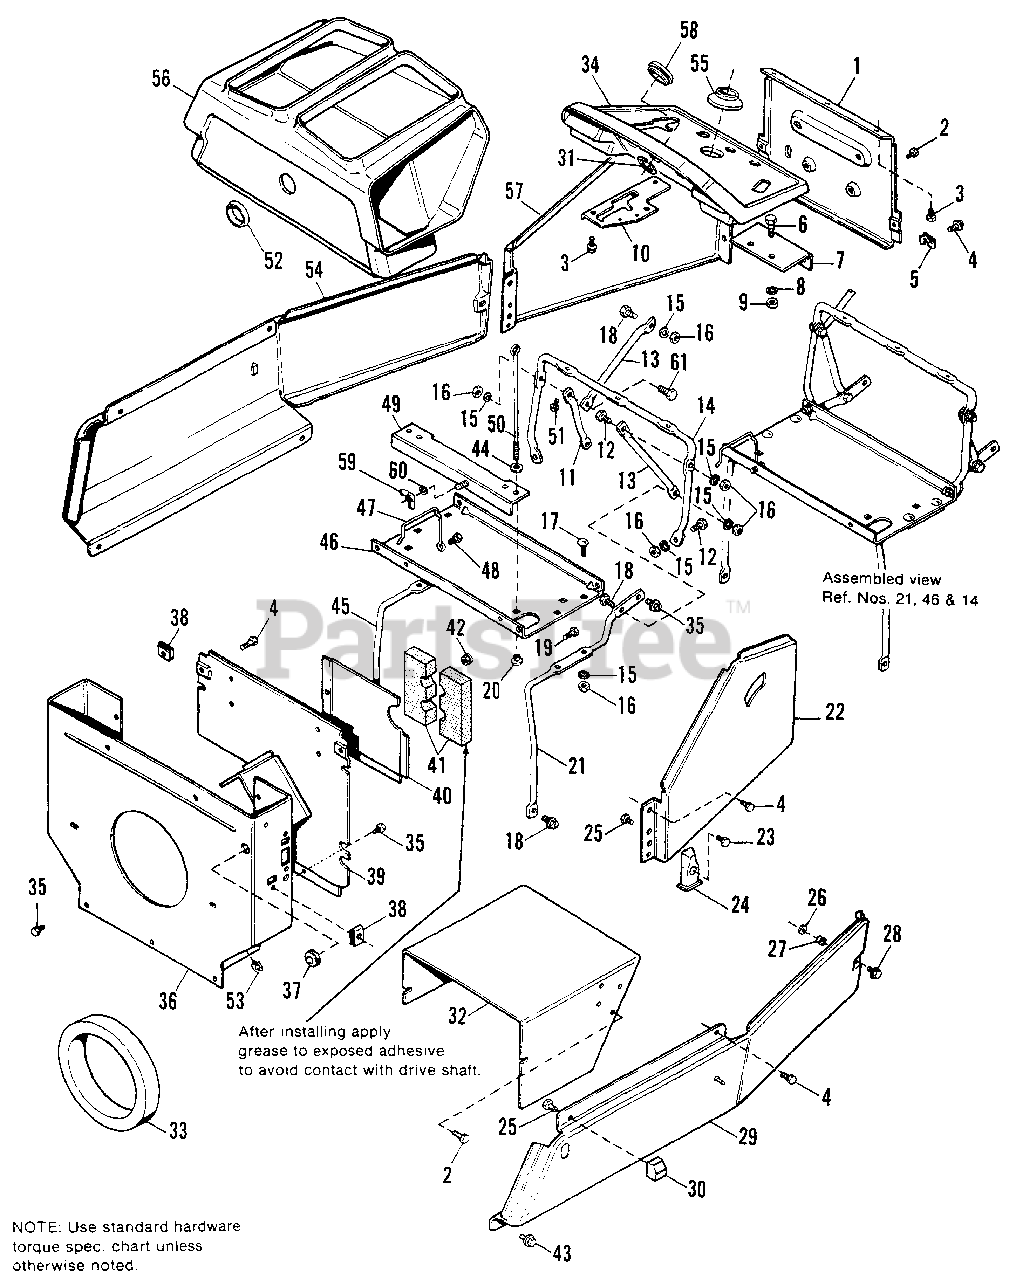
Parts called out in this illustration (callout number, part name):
1	PANEL, Rear Dash
2	SCREW, Hex, Taptite, 1/4-20 x 5/8 (Qty. 7 on 1691381 & 1691710 only)
3	SCREW, Hex, Plastite, 1/4-10 x 5/8
4	SCREW, Hex, Type "AB" 1/4-14 x 5/8
5	SPEED NUT, "J" Type, 14A
6	CAPSCREW, Hex Hd., 3/8-16 x 1
7	BRACKET, Mounting, Dash Panel, Rear
8	LOCKWASHER, 3/8
9	NUT, Hex, 3/8-16
10	PLATE, Speed Control Lever
11	BRACE, Dash Cap Support, R.H.
12	CAPSCREW, Hex Hd., 5/16-18 x 1
13	BRACE, Dash Cap Support, L.H.
14	SUPPORT, Dash Cap
15	LOCKWASHER, 5/16
16	NUT, Hex, 5/16-18
17	BOLT, Carriage, 5/16-18 x 7/8
18	CAPSCREW, Hex, Taptite, 5/16-18 x 3/4
19	CAPSCREW, Hex Hd., 1/4-20 x 3/4
20	NUT, Plastic, 1/4-20
21	SUPPORT, Battery Tray, L.H.
22	DASH PANEL, Upper, L.H.
23	SCREW, Hex, 1/4 x 1
24	GUIDE, Spacer, Hood
25	SCREW, Hex, Plastite, #10-14 x 1/2
26	PUSHNUT, .250
27	SPACER, Side Panel
28	SCREW, Hex, Taptite, 1/4-20 x 1
29	PANEL ASSY., L.H.
30	SPACER, Hood/Side Panel
31	RING, Spiral, Retaining (1691250, 1691357 only)
32	COVER, Tunnel (1691250, 1691357, 1691380, 1691528, 1691924 only)
32	COVER, Tunnel (1691381, 1691710, 1691926, 1691928, 1691953 only)
33	SEAL, Engine, Bulkhead (All models except 1691250 & 1691357)
33	SEAL, Engine Bulkhead (1691250, 1691357 only)
34	CAP, Dash (all models except 1691710, 1691928)
34	CAP, Dash (1691710, 1691928 only)
35	SCREW, Hex, Taptite, 5/16-18 x 3/4
37	GROMMET, 1/2" I.D. (all models except 1691250, 1691357)
38	SPEED NUT, "U" Type, 14A
39	PANEL ASSY., Bulkhead
40	PANEL, Clean Out
41	SEAL, Drive Shaft
42	NUT, Hex, Flange Whizlock, 1/4-20
43	SCREW, Hex, Taptite, 1/4-20 x 5/8 (Qty. 3 on 1691381, 1691710, 1691926, 1691928)
44	WASHER, Plain, 1/4 x 5/8 x 3/64
45	SUPPORT, Battery Tray, R.H.
46	TRAY, Battery
47	GUIDE, Plenum
48	SCREW, Hex, Taptite, 1/4-20 x 1/2
49	HOLD DOWN, Battery
50	ROD, Battery Hold Down
51	SCREW, Hex, Plastite, 1/4-10 x 3/4
52	PLUG, Hole, Plenum (1691250, 1691357 only)
53	CLIP, Routing, Snapin, (1691250, 1691357 only)
54	LOWER PANEL ASSY., R.H.
55	BOOT, Steering Stem
56	PLENUM, Air Induction
57	DASH PANEL, Upper, R.H.
58	CAP (1691250, 1691357 only)
59	NUT, Wing, 1/4-20
60	WASHER, 1/4
61	CAPSCREW, Hex, 5/16-18 x 1-1/4
